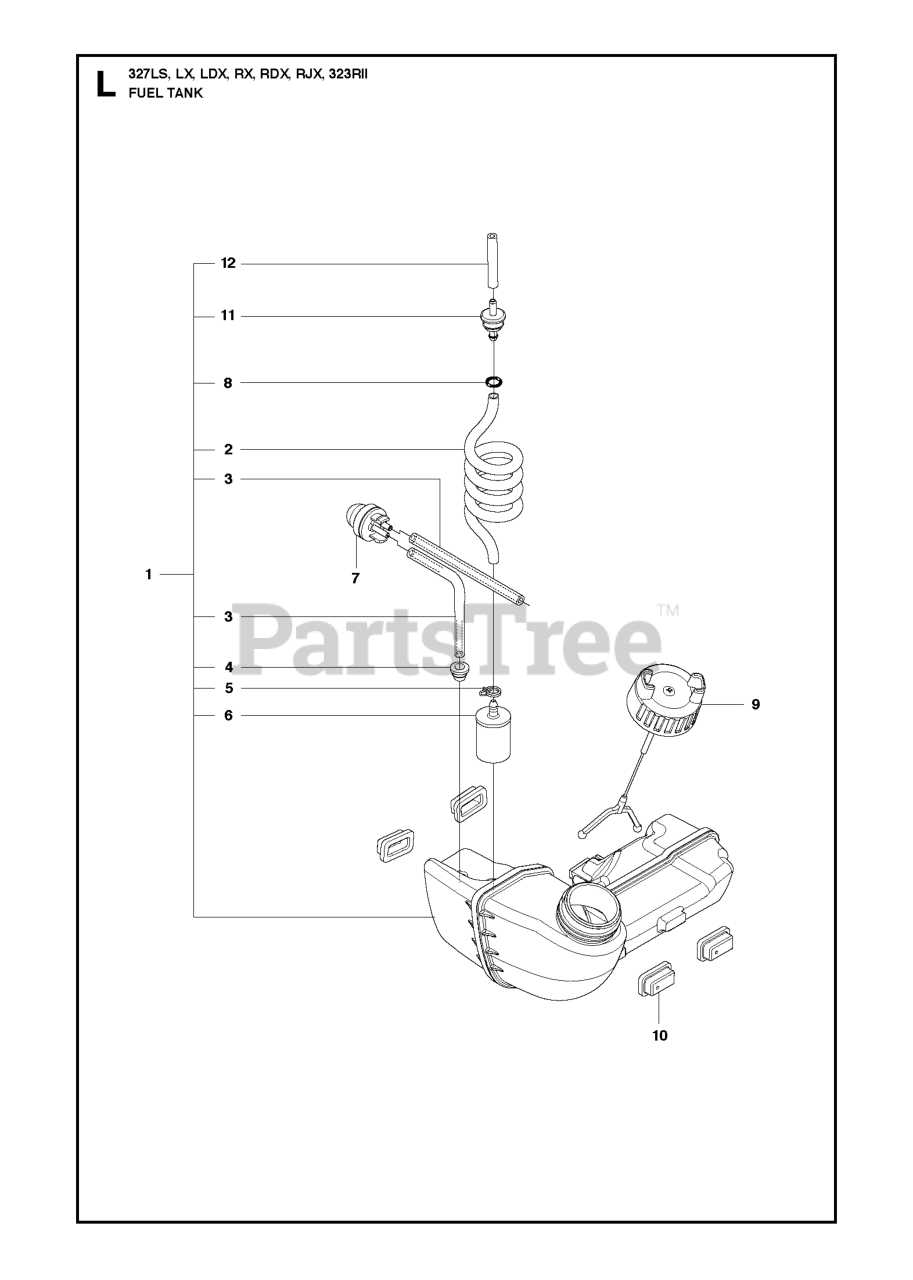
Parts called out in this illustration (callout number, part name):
1	FUEL TANK ASSY
3	HOSE.FUEL L=102
4	FUEL TANK BUSHING
5	HOSE CLAMP
6	RP FUEL FILTER
7	AIR PURGE BUBBLE
9	TANK CAP
11	HOSE NIPPLE
12	FUEL HOSE
